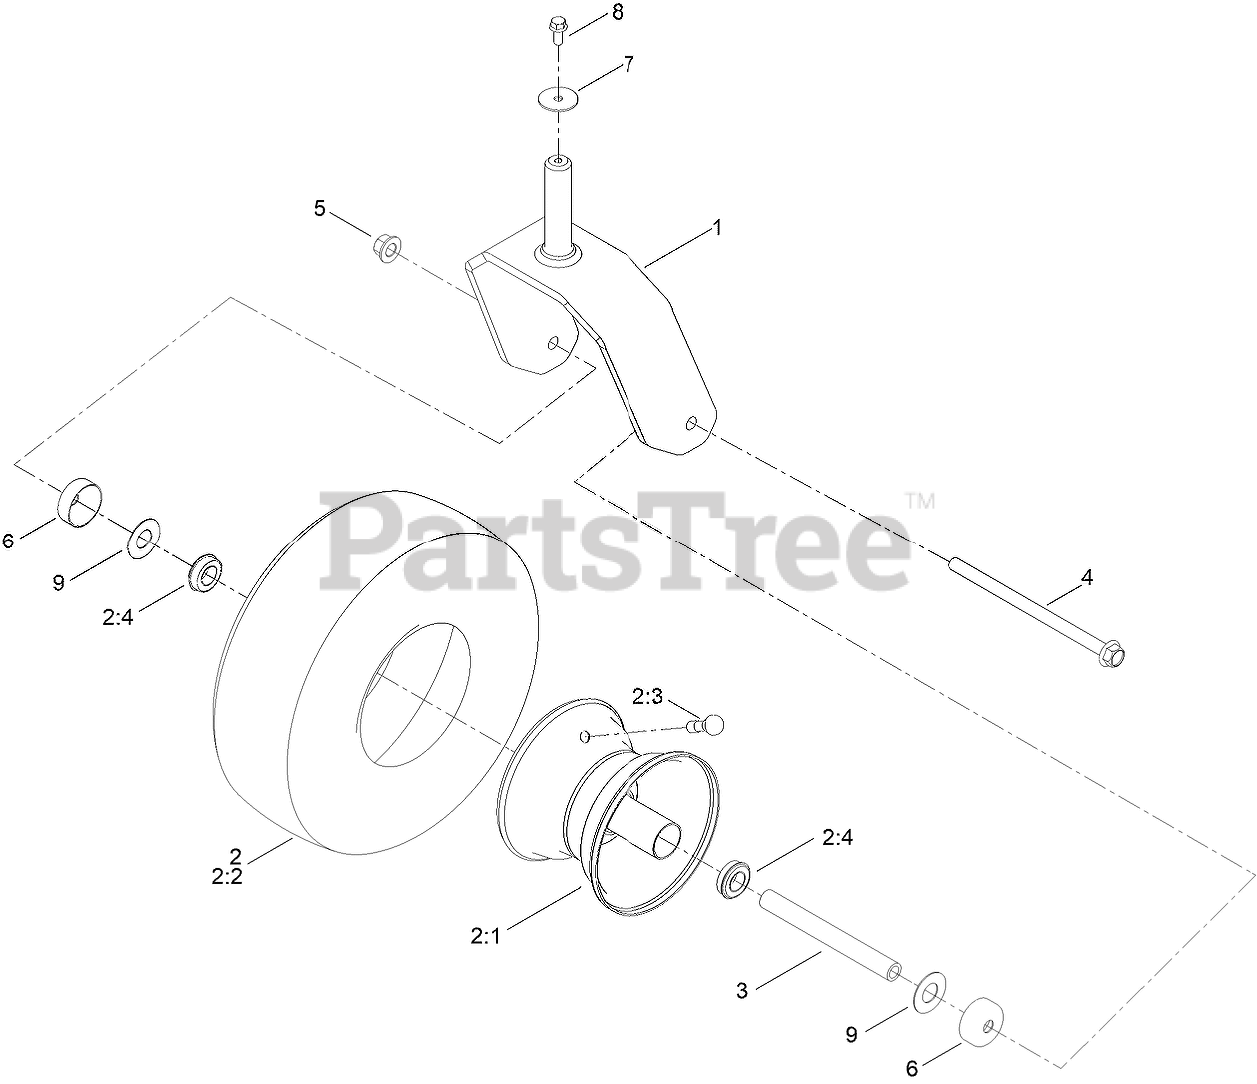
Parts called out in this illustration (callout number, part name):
1	FORK-CASTER
2	TIRE AND WHEEL ASM
2:1	RIM-6"
2:4	BEARING
3	SPANNER-WHEEL
4	SCREW-HHF
5	NUT-LOCK
6	GUARD-SEAL
7	WASHER-FLAT
8	SCREW-HHF
9	WASHER
